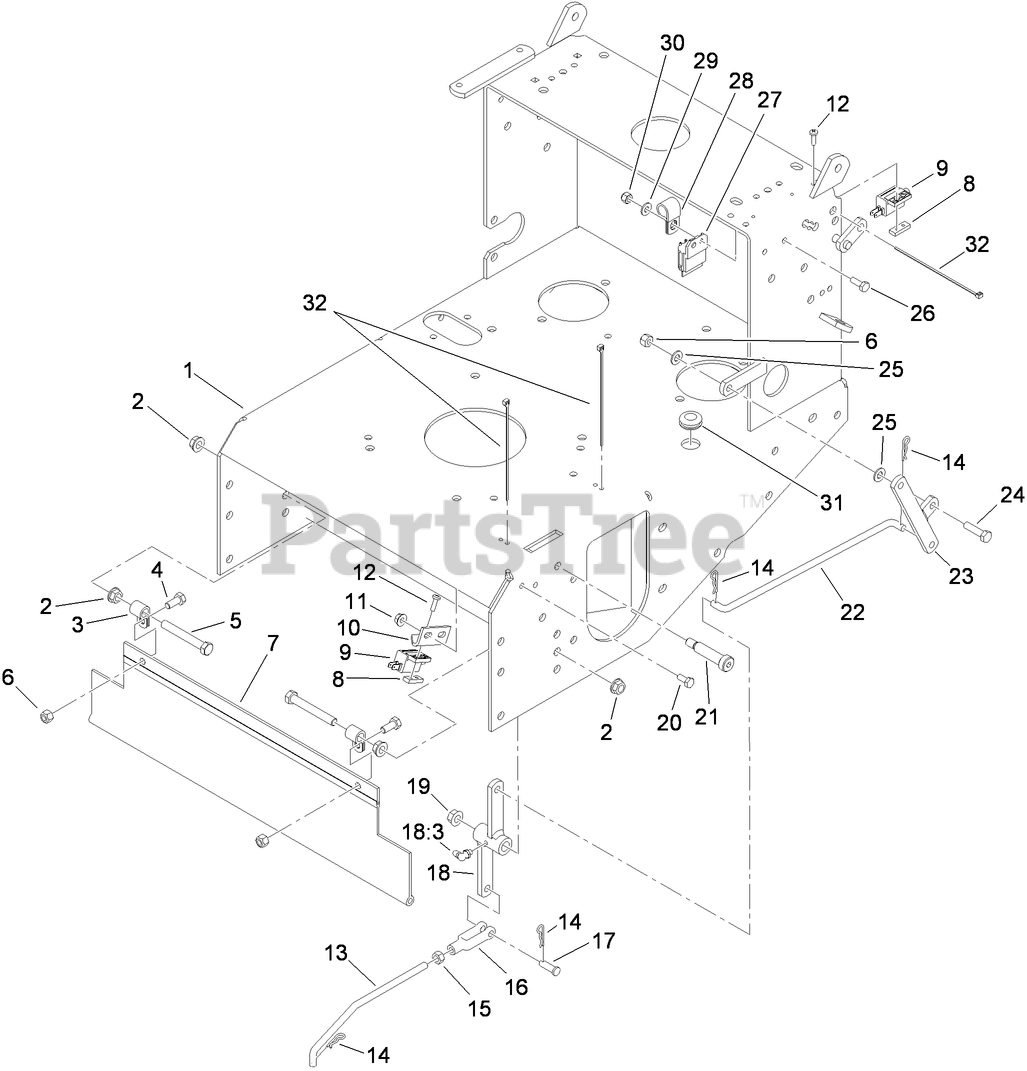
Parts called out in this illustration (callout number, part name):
1	HYDRO FRAME ASM
2	NUT-HHF, WHIZ
3	Clip-Loom
4	SCREW-HH
5	SCREW-HH
6	NUT-LOCK, NI
7	Shield-Drag
8	PLATE-TAPPED
9	SWITCH-OPEN, NORMALLY
10	Bracket-Switch, Blade
11	NUT-HF
12	SCREW-PPH
13	ARM-LINKAGE, ASSIST
14	PIN-COTTER
15	NUT-HEX
16	YOKE-ADJUSTABLE
17	PIN-CLEVIS
18	Bellcrank ASM
18:3	FITTING-GREASE, 90 DEG
19	NUT-HF
20	SCREW-HH
22	Linkage-Engage, Blade
23	BELLCRANK ASM
24	SCREW-HH
25	WASHER-PLAIN
26	SCREW-HH
27	MODULE-INTERLOCK
28	CLIP-LOOM
29	WASHER-FLAT
30	NUT-LOCK, NI
31	GROMMET
32	TIE-CABLE
